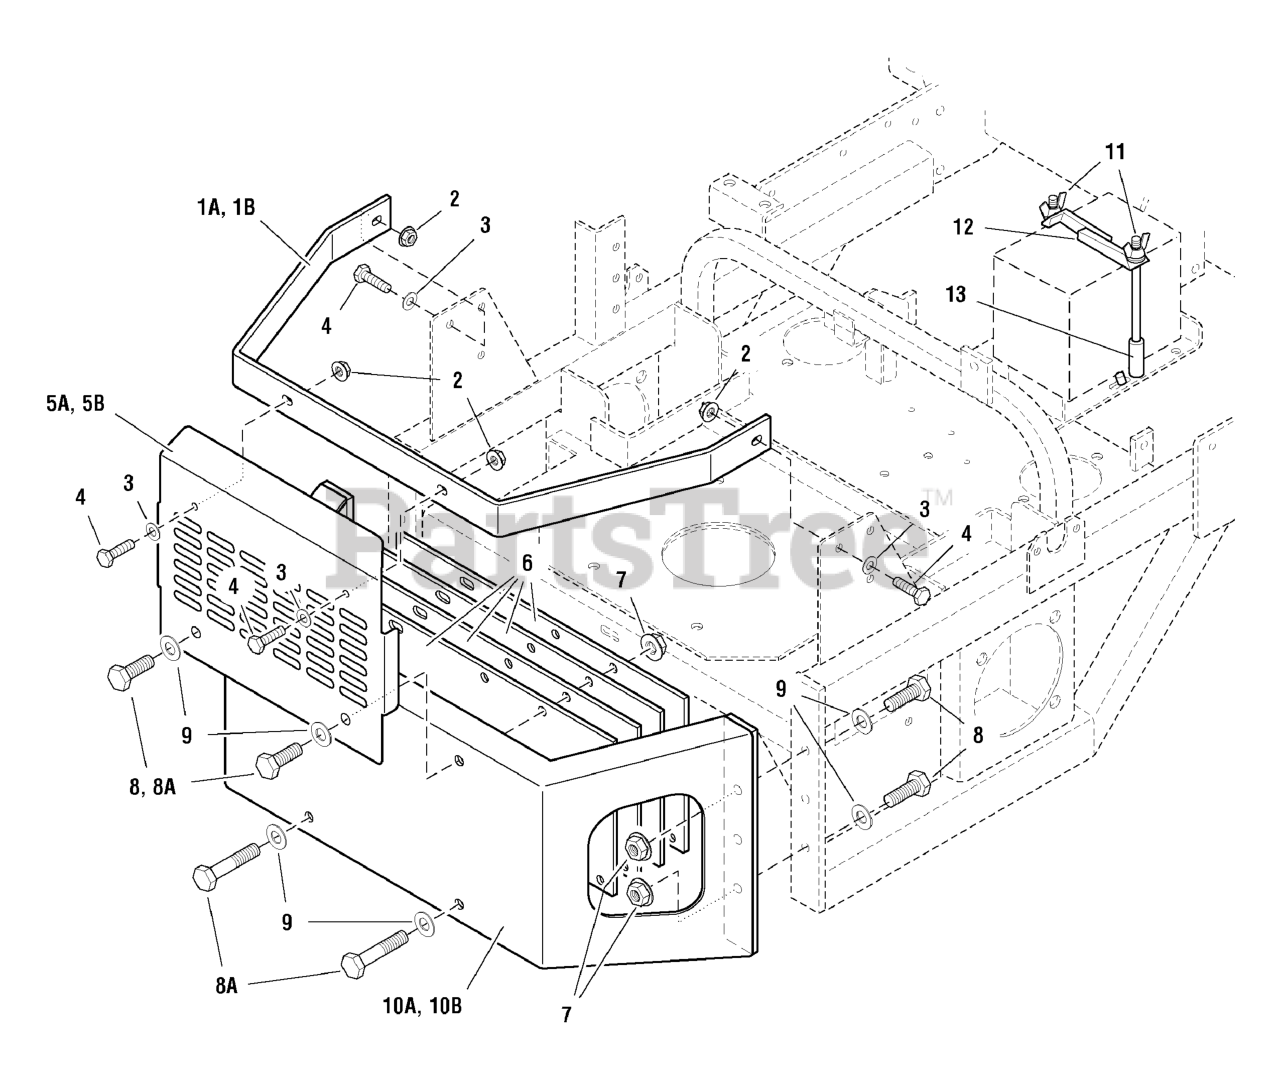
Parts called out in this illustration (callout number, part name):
1A	BUMPER BAR
1B	BUMPER BAR
2	NUT, 5/16-18 HEX SERRATED FLANGE (LARGE)
3	WASHER, 5/16" SAE
4	BOLT, 5/16-18 X 1 GD5 YZ
5A	BUMPER SHIELD
5B	BUMPER SHIELD
6	COUNTERWEIGHT
7	NUT, 3/8-16 Hex Serrated Flange
8	BOLT, 3/8-16 X 1" GD5 CZ
8A	BOLT, 3/8-16 X 2, GD5, CZ
9	WASHER, 3/8 SAE
10A	BUMPER
10B	BUMPER
11	BATTERY HOLDDOWN BOLT
12	BATTERY HOLDDOWN
13	1/4" Fuel Line, 3" Long
